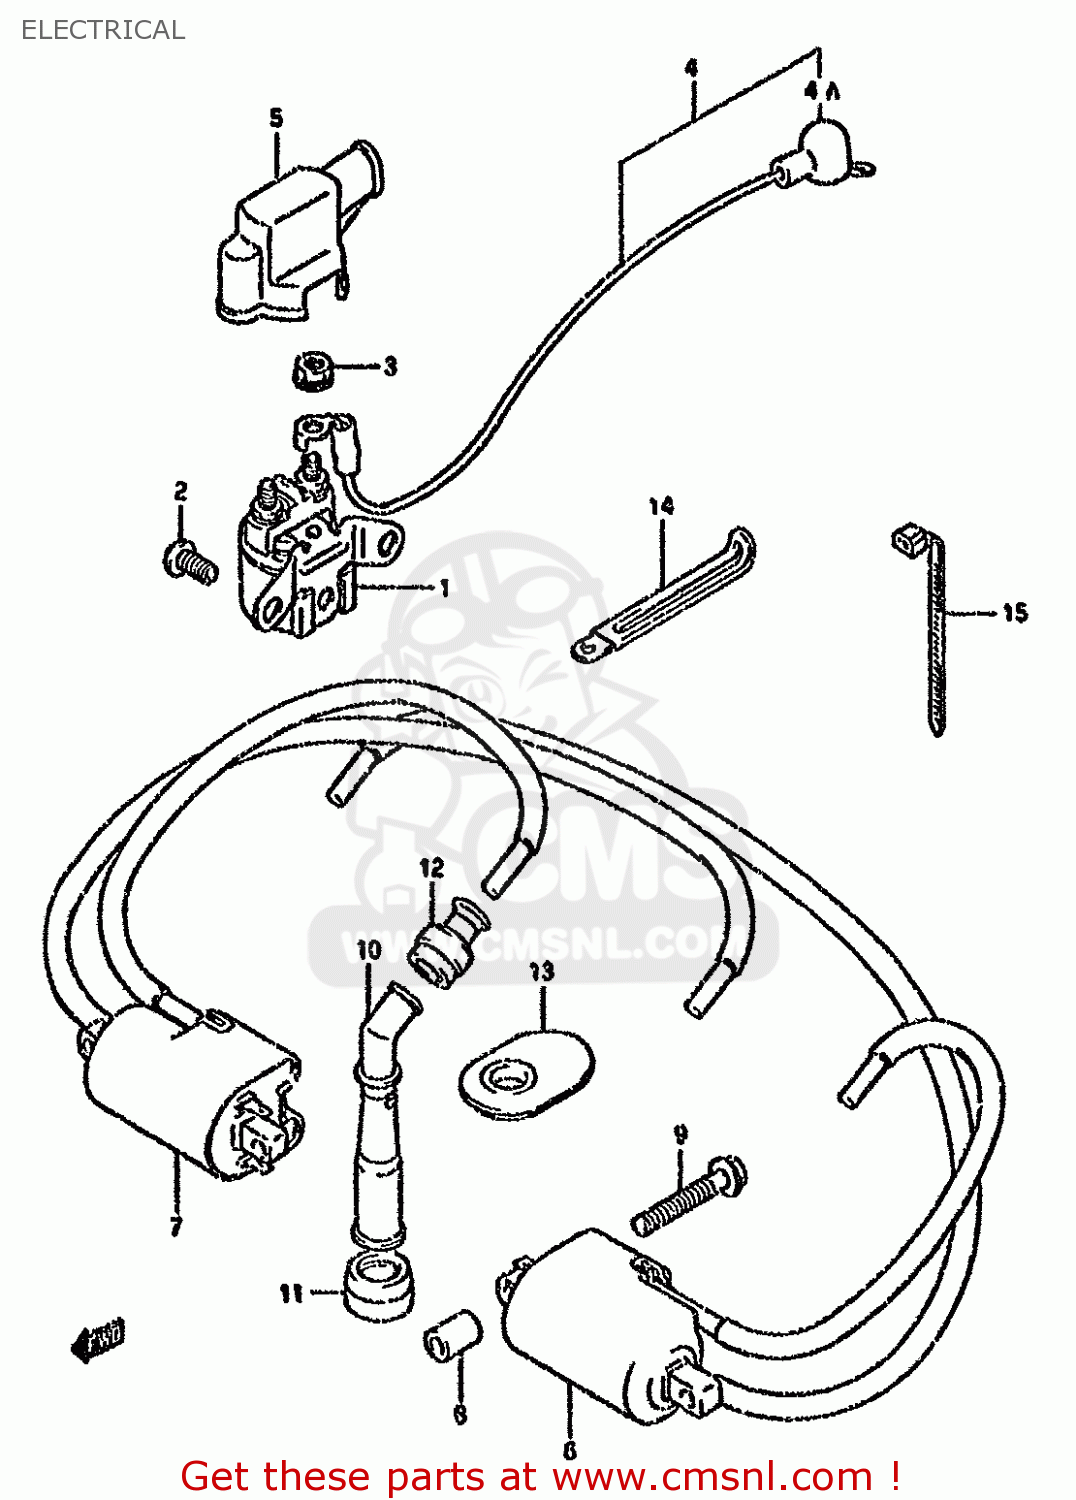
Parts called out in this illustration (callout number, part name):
1	RELAY ASSY,STARTING MOTOR
2	SCREW
3	NUT
4	WIRE,STARTER MOTOR LEAD
4A	CAP,STARTER MOTOR LEAD
5	CAP,STARTER RELAY
6	COIL ASSEMBLY,IGNITION NO
7	COIL ASSEMBLY,IGNITION NO
8	SPACER(6.2X12X16)
9	SCREW
10	CAP,SPARK PLUG
11	SEAL,SPARK PLUG
12	SEAL,HIGH TENSION CORD
13	COVER,SPARK PLUG CAP
14	CLAMP
15	CLAMP(L:165)
